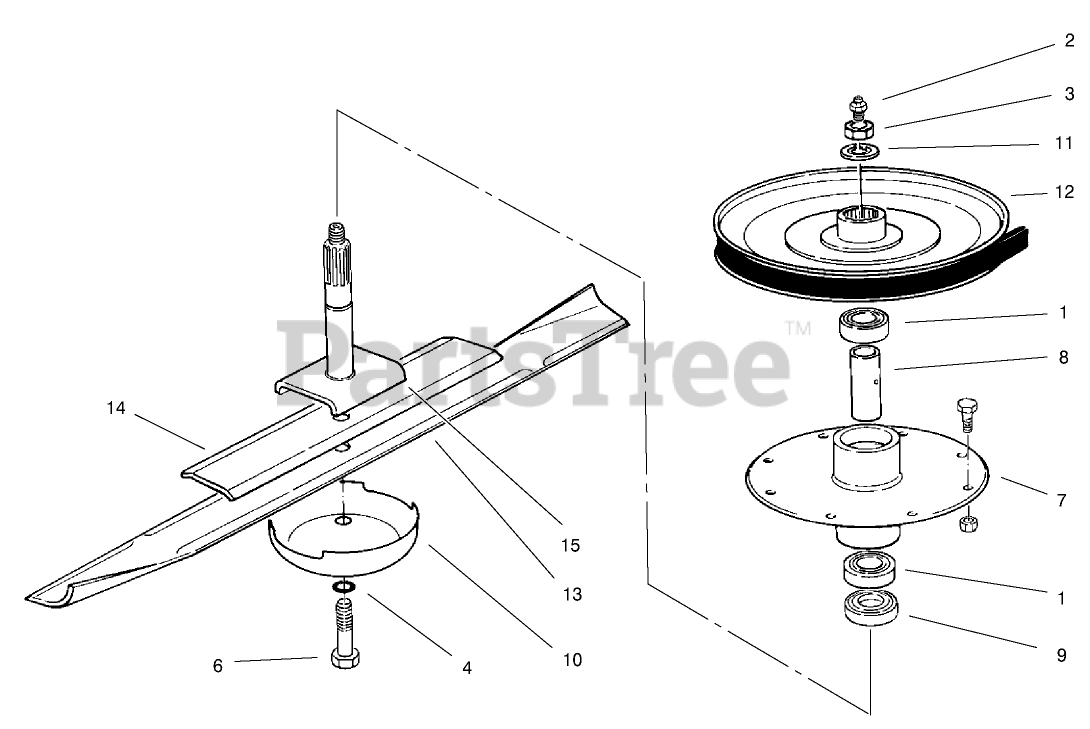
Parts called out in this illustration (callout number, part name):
1	BEARING-BALL
2	FITTING-GREASE
3	NUT-HEX
4	WASHER-LOCK/SP
6	SCREW-BLADE
7	HOUSING-SPINDLE
8	SPACER-BEARING
9	SPACER
10	Cup
11	WASHER
12	PULLEY ASM
13	BLADE-RECYCLER
14	Decal-Danger
15	SHAFT-SPINDLE
